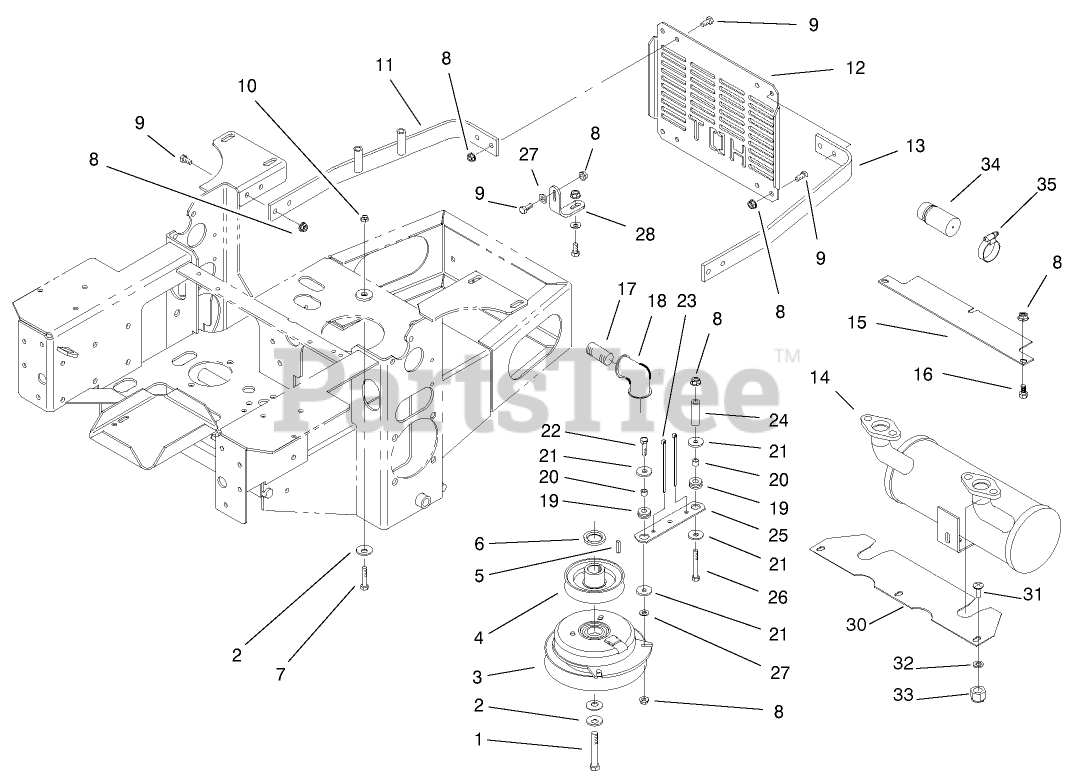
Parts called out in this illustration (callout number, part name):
1	SCREW-HH
2	WASHER-SPRING
3	Clutch,Mag Stop
4	PULLEY
6	SPACER-CRANKSHAFT
7	SCREW-HH
8	NUT-HF
9	SCREW-HH
10	NUT-HF
11	STRAP-GUARD, ENGINE
12	SHIELD-ENGINE
13	STRAP-GUARD, ENGINE
14	Muffler (only on:74172, 74174, 74178, 74197, 74171)
15	Deflector,Lower Frame
16	SCREW-HH
17	NIPPLE,PIPE
18	ELBOW-90 DEG
19	GROMMET
20	SPACER
21	WASHER
22	SCREW-HH
23	TIE-PLASTIC
24	BUSHING-MOUNT, SEAT
25	STRAP-CLUTCH, BRAKE
26	SCREW-HH
27	WASHER-FLAT
28	BRACKET-SUPPORT, MUFFLER
30	Shield,Heat
31	BOLT-CARR
32	WASHER-PLAIN
33	NUT-LOCK, NI
34	ARRESTER-SPARK
35	CLAMP-MUFFLER
